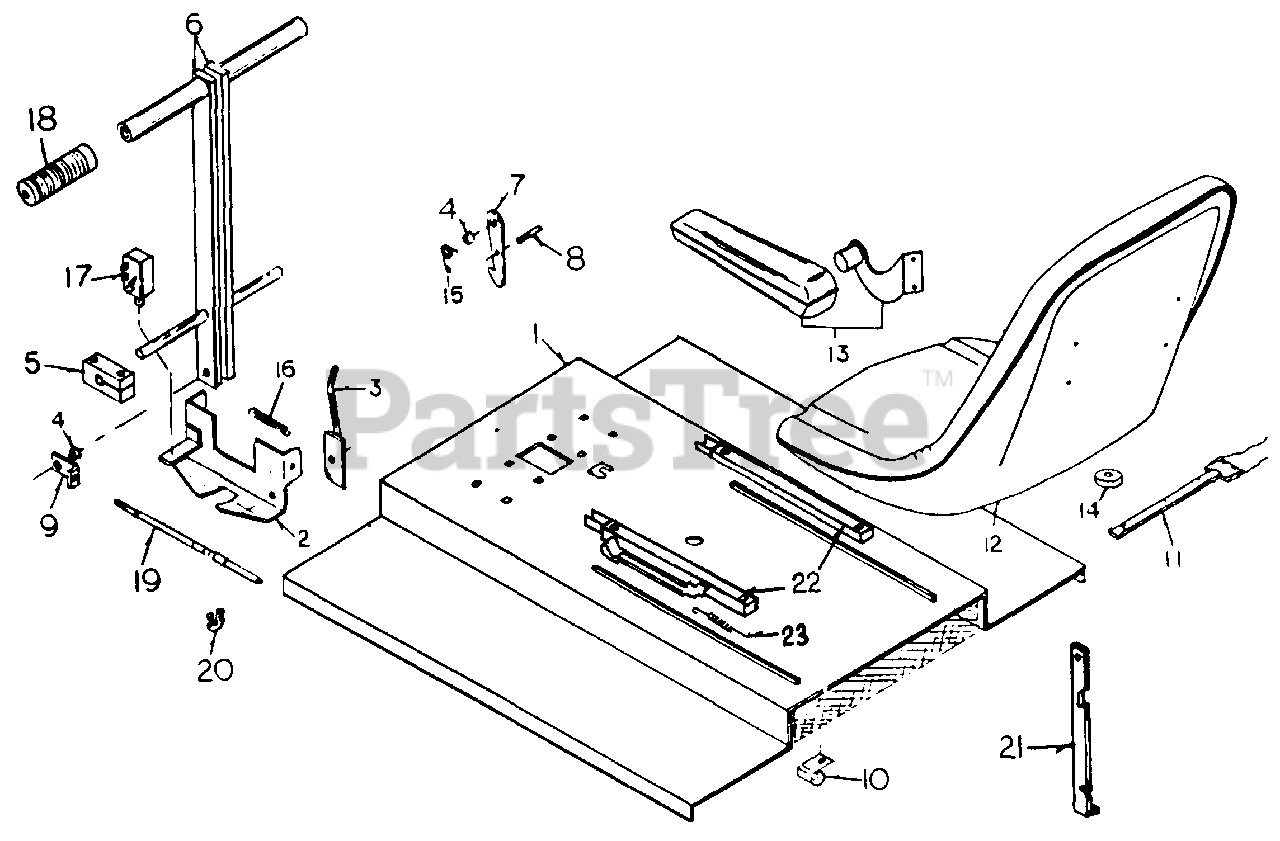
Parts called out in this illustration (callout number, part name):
3	Latch, Lever Lock
4	Bushing
6	Steering Lever
7	Seat Lid Latch
8	Seat Lid Latch Bolt
9	Steering Cable End
10	Seat Lid Harness Retainer
13	Arm Rest Kit
15	Seat Lid Latch Spring
16	Lever Lock Spring
18	Handle Grip
19	Steering Cable
20	Steering Cable Clamp
22	Seat Rail Kit
